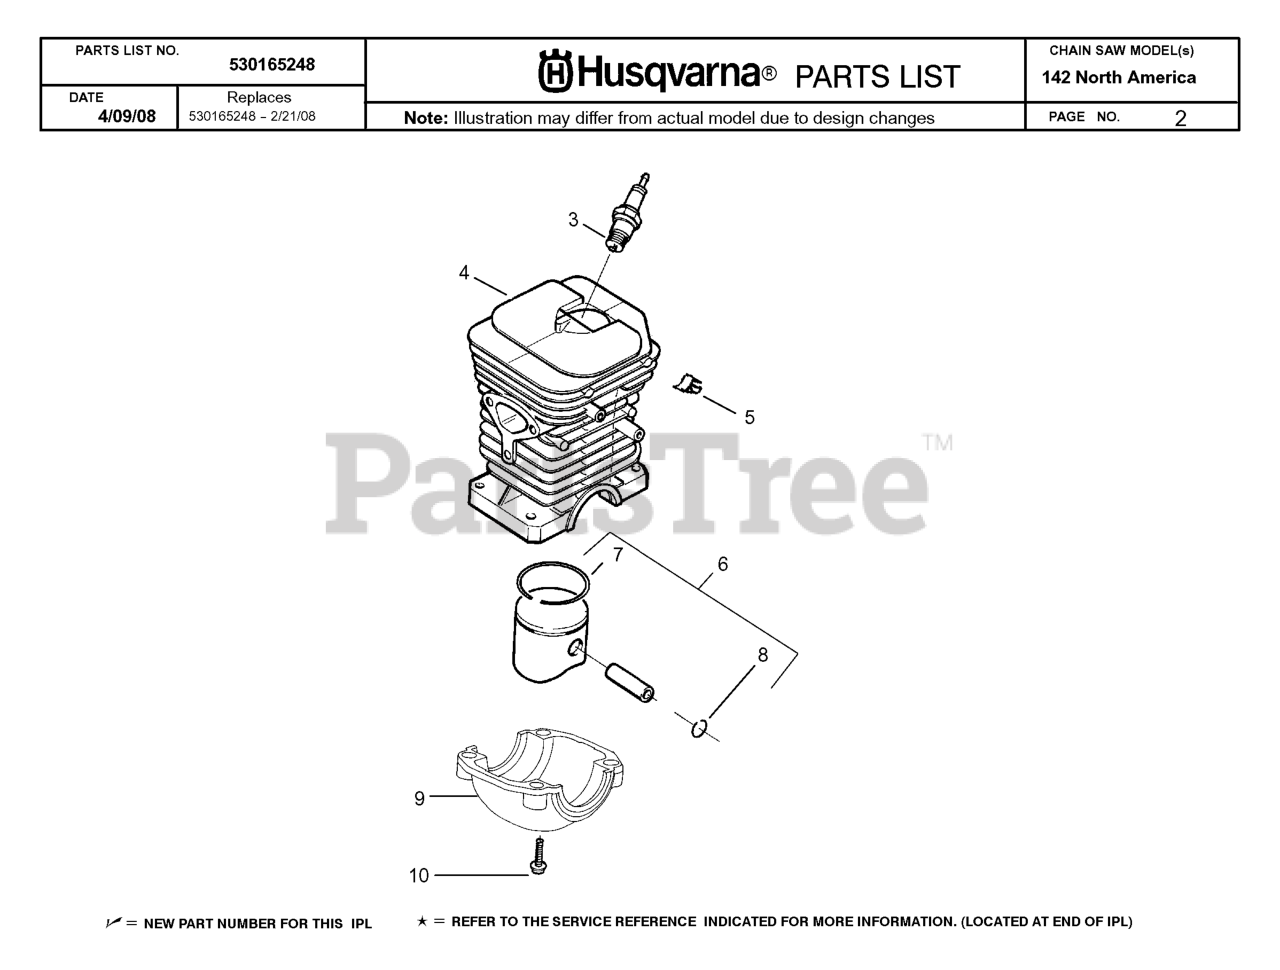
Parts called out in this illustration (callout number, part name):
3	Spark Plug (RCJ--7Y)
4	CYLINDER ASSY/141
5	CLIP - HIGH TENSION LE
6	KIT-PISTON
7	PISTON RING HV41
8	C-CLIP,PSTN PIN 36/41
9	CAP-CRANKSHAFT
10	SCREW-M5-0.8 X 25MM(TAP)
